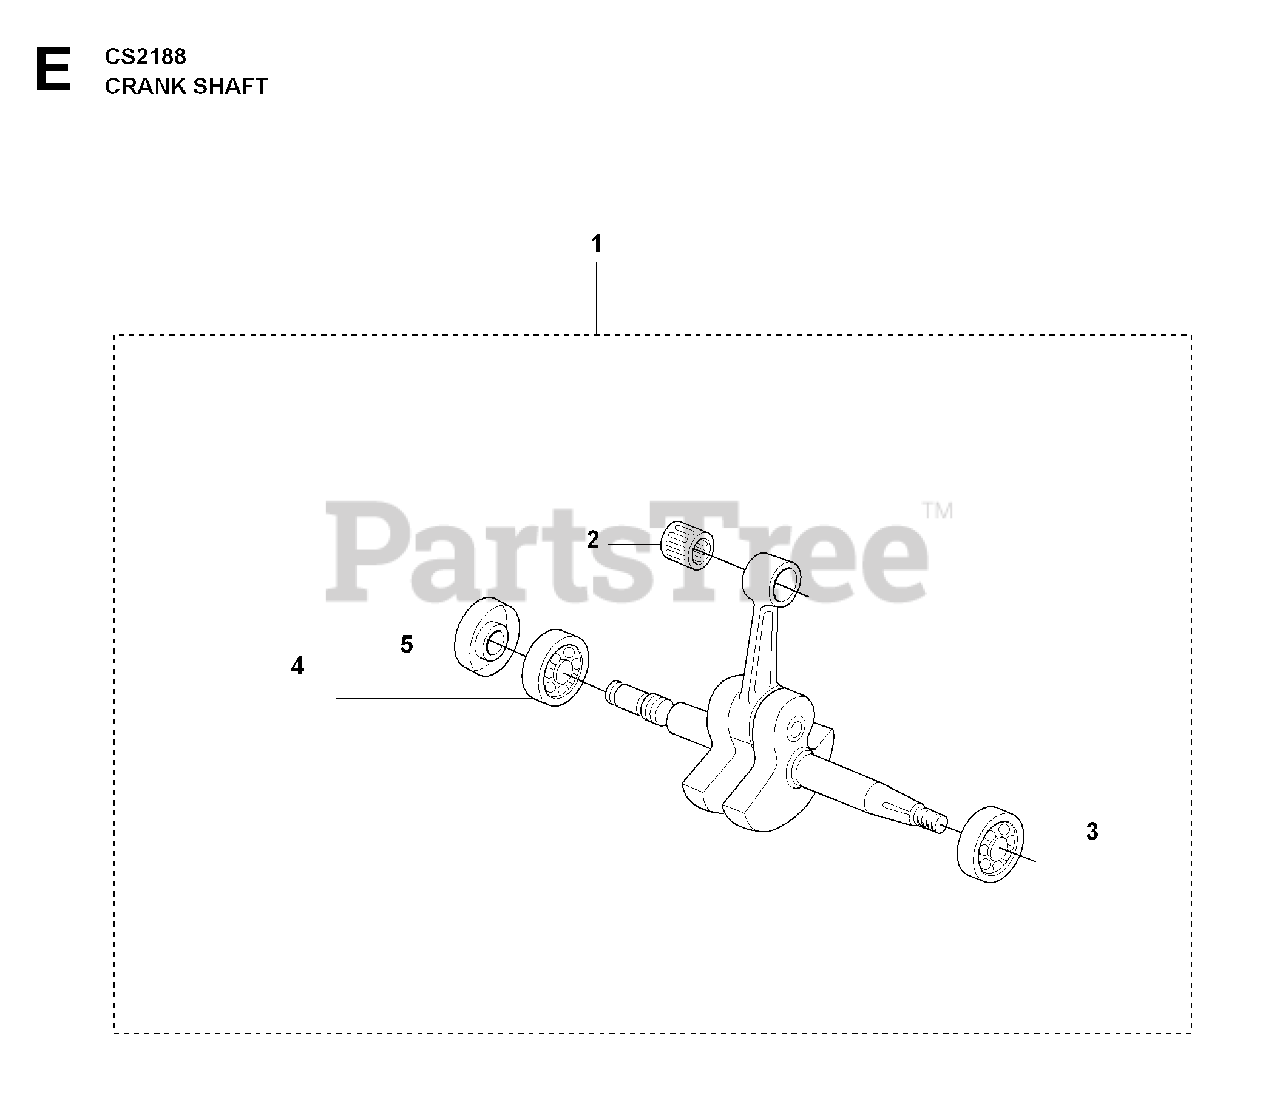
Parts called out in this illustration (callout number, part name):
1	CRANKSHAFT
2	SUPPORT BUSHING
3	BALL BEARING 6203 C3
4	BALL BEARING
5	SEALING RING
